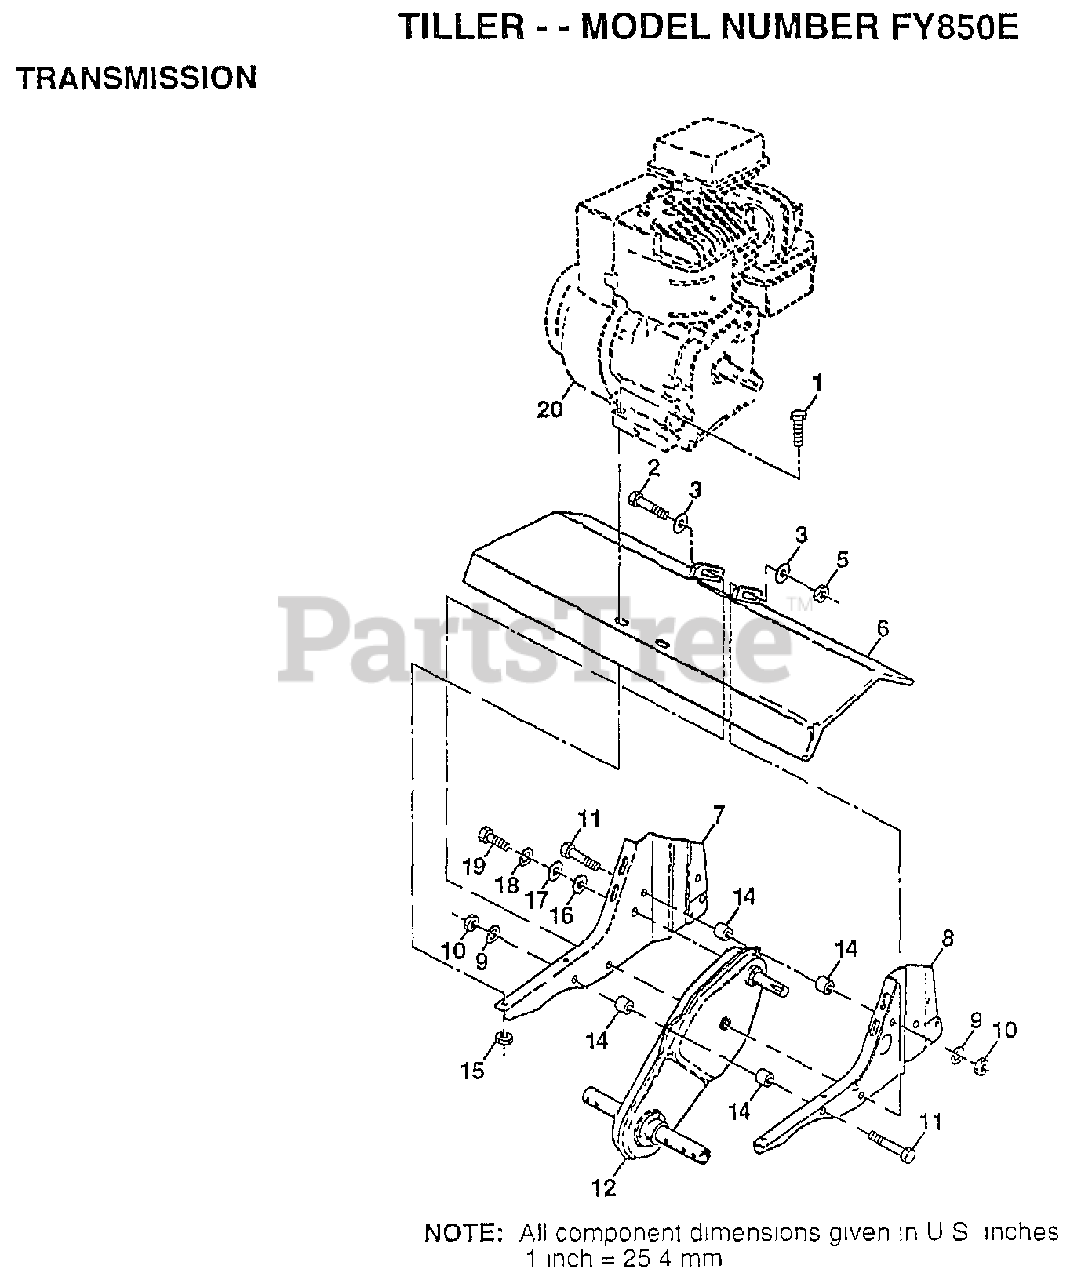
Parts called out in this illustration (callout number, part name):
1	BOLT.HEX.5/16-1.5
2	BOLT HEX 3/8-16
3	WASHER
5	NUT
6	"SHIELD, TINE"
8	BRACKET.ENG.LH.
9	LOCKWASHER
10	NUT.HEX.5/16-18
14	SPLIT SPACER RT
16	WASHER
17	WASHER
18	LOCKWASHER
19	BOLT
